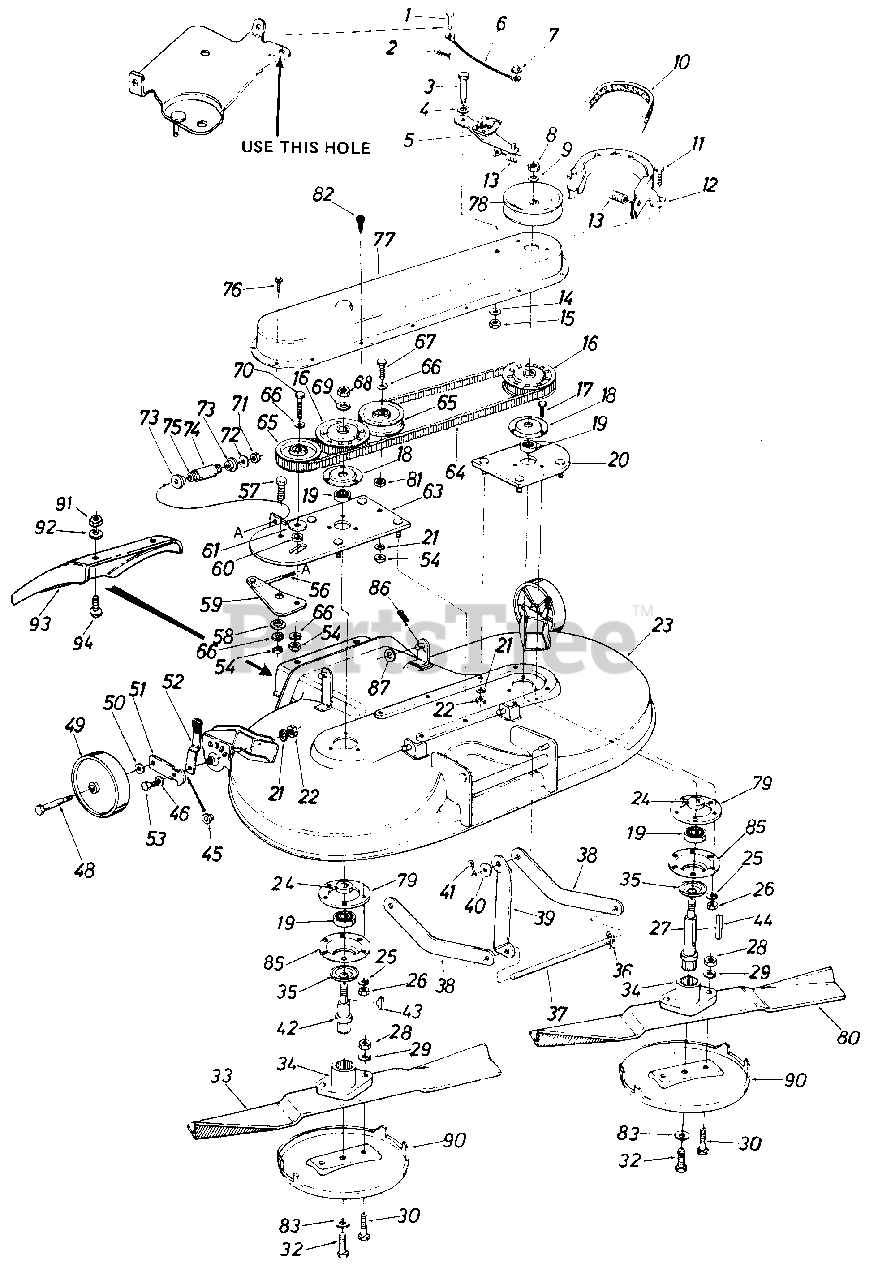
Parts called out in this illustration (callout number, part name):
1	Clevis Pin 1/4" Dia. x 1/2" Lg.
2	Hairpin Coter 1/4" Dia.
3	Shld. Bolt .437" Dia. x .180" Lg. (5/16-18)
4	Wave Washer 7/16" Scr.
5	Spindle Brake Arm Ass'y.
6	Brake Cable Ass'y.
7	Push Cap 1/4" Stud.
8	Hex Jam Nut 5/8-18 Thd.
9	Bell.Wash. 5/8" I.D. x 1.25" O.D.
10	"V" Belt
11	Hex Wash. Hd. Self Tap Scr. 1/4-20 x .50" Lg.
12	Belt Guard
13	Extension Spring
14	Bell.Wash. .340" I.D.
15	Hex Cent. L-Nut 5/16-18 Thd.
16	Sprocket Pulley Ass'y.
17	Hex Bolt 5/16-24 x 1.00" Lg.(Grade 5)
18	Bearing Housing
19	Ball Bearing .787" I.D. x 1.85" O.D.
20	Spindle Plate Ass'y.
21	L.Wash. 3/8" I.D.*
22	Hex Jam Nut 3/8-24 Thd.
23	44" R.G. Deck Ass'y.
24	Spacer
25	L.Wash. 5/16" I.D.*
26	Hex Nut 5/16-24 Thd.*
27	Blade Spindle-L.H.
28	Hex Nut 5/16-24 Thd.*
29	L.Wash. 5/16" I.D.*
30	Hex Bolt 5/16-24 x 1.00" Lg.
32	Hex Bolt Cent. L.3/8 x 24 x 88" Lg.
33	22.5" Blade-L.H. Rotation
34	Blade Adapter
35	Bearing Shield
36	Hairpin Coter
37	Deck Connecting Rod
41	Coter Pin 3/32" Dia. x 1.00" Lg.
42	Blade Spindle-R.H.
43	Sq. Key 3/16" x 75" Lg.*
44	Sq. Key 3/16" x 1.50" Lg.*
45	Shoulder Spacer
46	Bell.Wash. .400" I.D.
48	Shld. Bolt 3/8-16 x 1.41" Lg.
49	Wheel Ass'y. Comp. 6" x 1.38
50	Bell-Wash. 3/8" I.D.
51	Wheel Pivot Bar
52	Spring Lever Ass'y. w/knob
53	Hex Bolt 3/8-24 x 1.25" Lg. Grade 5
54	Hex Cent. L-Nut 3/8-24 Thd.
56	Adjustment Link 5/16-18 x 4-9/16" Lg.
57	Hex Bolt 3/8-24 x 1.00"
58	Shld. Spacer.625" I.D.
59	Belt Idler Brkt.
60	Spacer.380" I.D. x .625" O.D. x .265
61	Fl.Wash. .38" I.D. x 1.37" O.D. x .125
63	Spindle & Idler Mount Plate Ass'y.
64	HTD Twin Power Belt
65	Fl.ldler Pulley 3.50" O.D.
66	Bell.Wash. .38" I.D.
67	Hex Bolt 3/8-24 x 1.75" Lg.(Grade 5)
68	Hex Jam Nut 5/8-18 Thd.*
69	Bell.Wash. 5/8" I.D.
70	Hex Bolt 3/8-24 x 2.00" Lg.
71	Hex Insert L.Nut5/16-18Thd.
72	Fl.Wash. 344" I.D. x 1.125" O.D. x .125
73	Shld. Spacer.625" I.D.
74	Spacer-Adj. Bolt
75	Compression Spring
76	Hex Wash. Hd. Self Tap Scr. 1/4-20 x .50" Lg.
77	Belt Cover
78	Deck Drive Pulley
79	Deck Reinforcement Plate
80	22.5" Blade-R.H. Rotation
81	Fl.Wash. .38" I.D. x 1.00" O.D.
82	Hex Wash. Hd. Self Tap-Scr. 1/4-20 x .75" Lg.
83	L.Wash. 3/8" I.D. Heavy Duty
86	Hairpin Coter
87	Fl.Wash. 1/2" I.D.
90	Anti-Scalp Plate
91	Hex Nut 1/4-20 Thd.*
92	L.Wash. 1/4" I.D.*
93	Chute Deflector
94	Truss Mach. Scr. 1/4-20 x .50" Lg.
